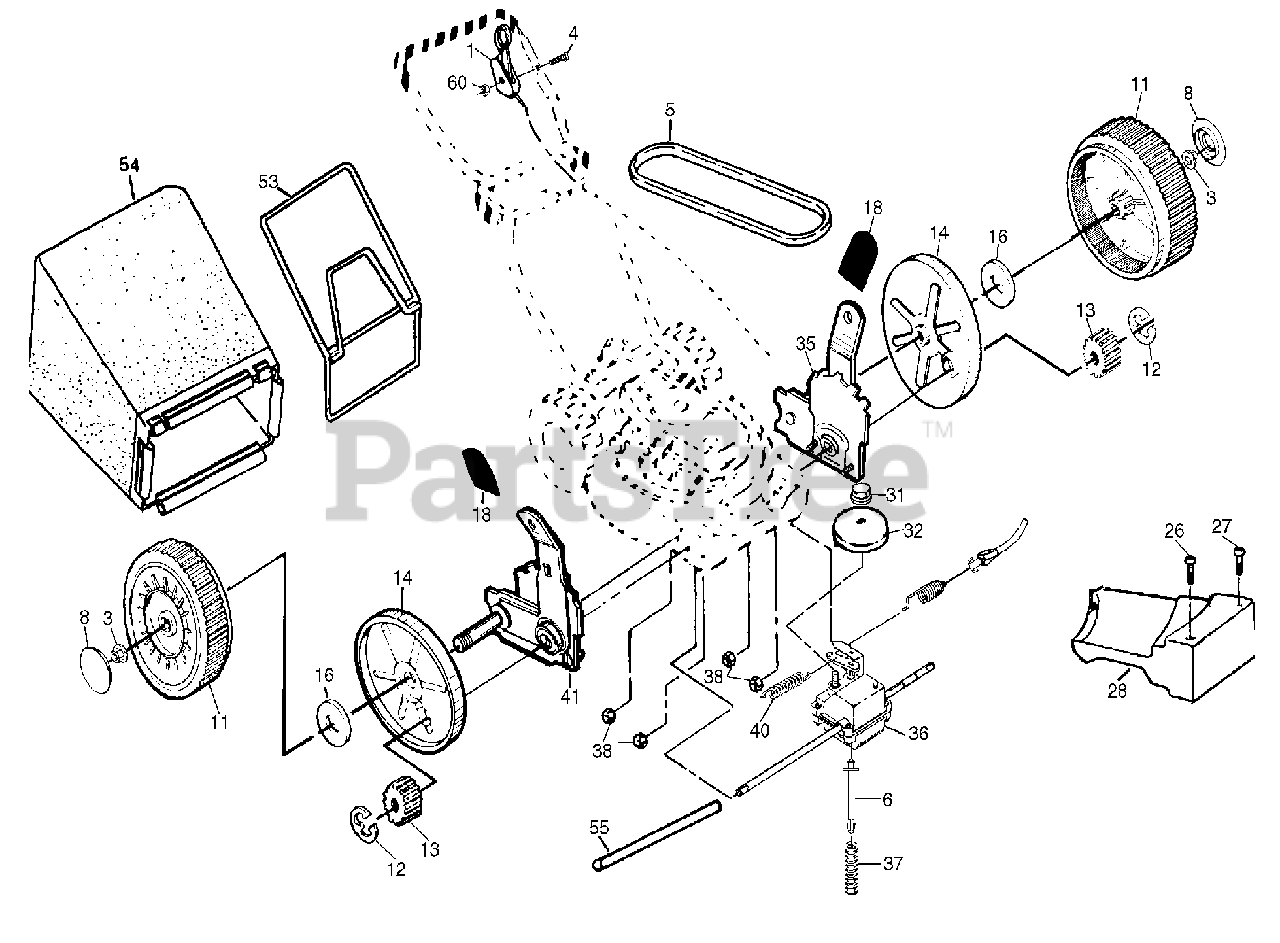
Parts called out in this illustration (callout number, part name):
1	Control Cable Assembly
3	Flanged Locknut 3/8-16
4	Hex Washer Head Screw 1/4-20 x 2.12
6	Spring Retainer
8	Hubcap
11	Wheel & Tire Assembly
12	E-Ring
13	Pinion
14	Dust Cover
16	Washer 1/2 x 1-1/2 x .134
18	Selector Knob
26	Pan Head Tapping Screw #10-24 x 2- 3/4
27	Pan Head Screw #10-24 x 1- 3/4
28	Drive Cover
31	Hex Flange Nut
32	Drive Pulley
35	Wheel Adjuster Assembly (Left)
36	Gear Case Assembly
37	Spring
38	Locknut 1/4-20
40	Spring
41	Wheel Adjuster Assembly (Right)
53	Frame Assembly
54	Grass Catcher
55	Driveshaft Cover
60	Nut
